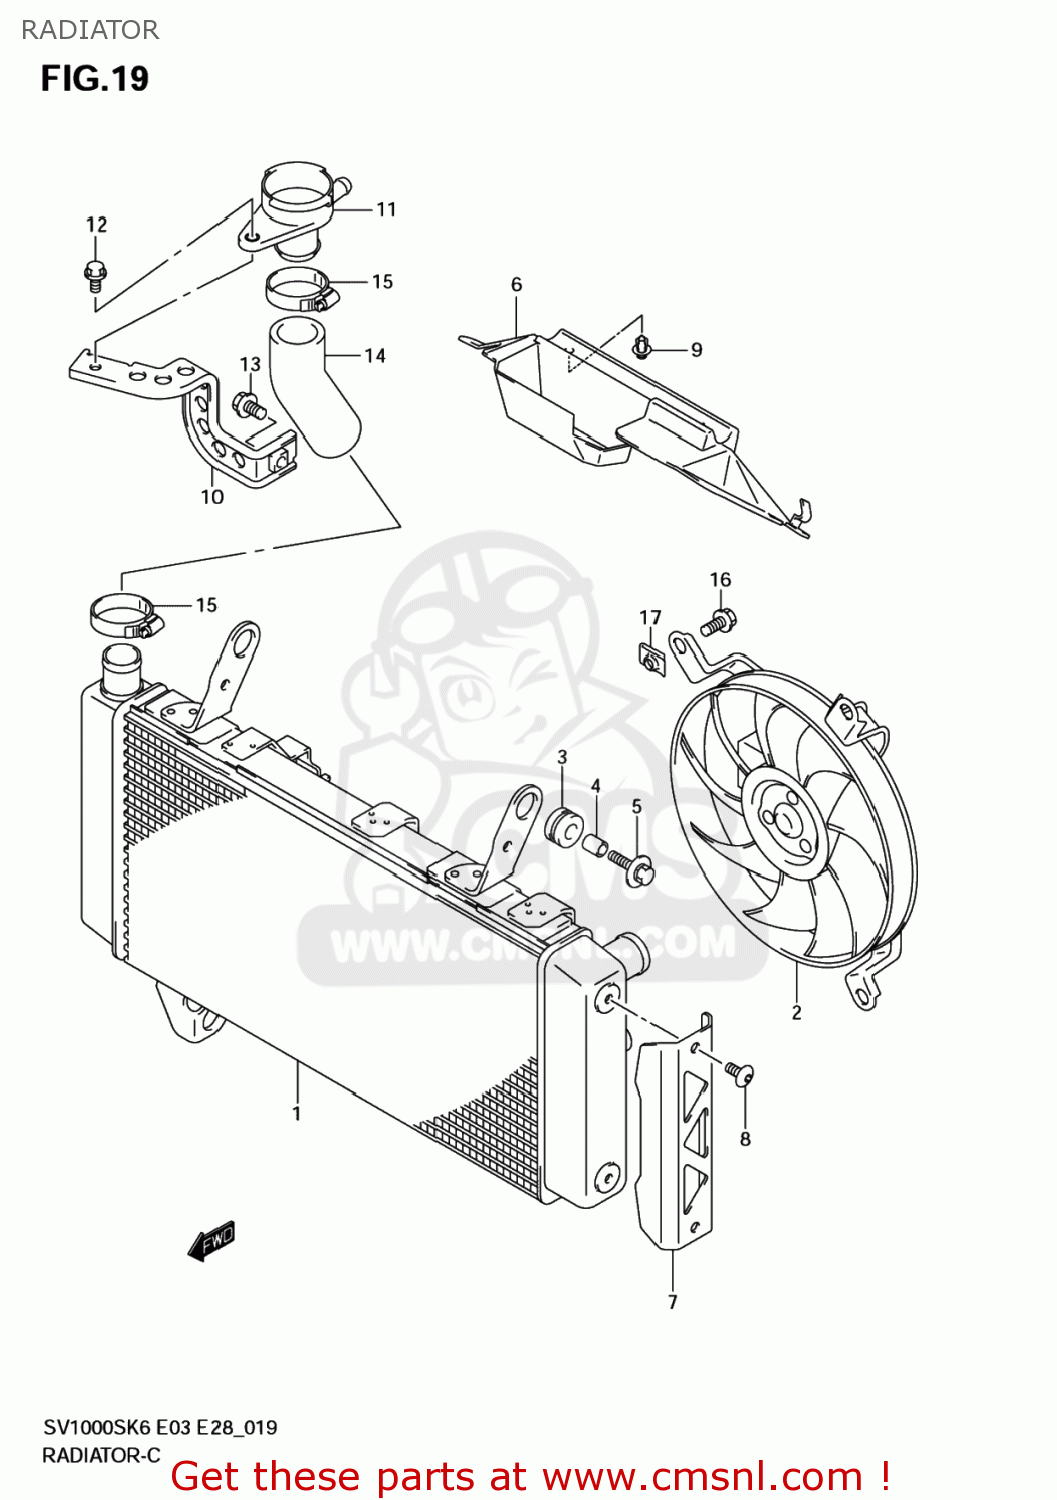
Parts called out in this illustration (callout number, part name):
1	RADIATOR ASSY,WATER
2	FAN ASSY,RADIATOR
3	CUSHION
4	SPACER(6.5X10X12)
5	BOLT(6X25)
6	SHIELD,RADIATOR HEAT
7	COVER,RADIATOR
8	SCREW(6X12)
9	CLIP
10	BRACKET,CONDUCTION
11	CONDUCTION,RADIATOR
12	BOLT
13	BOLT
14	HOSE,CONDUCTION
15	CLAMP
16	BOLT
17	NUT,RADIATOR FAN
